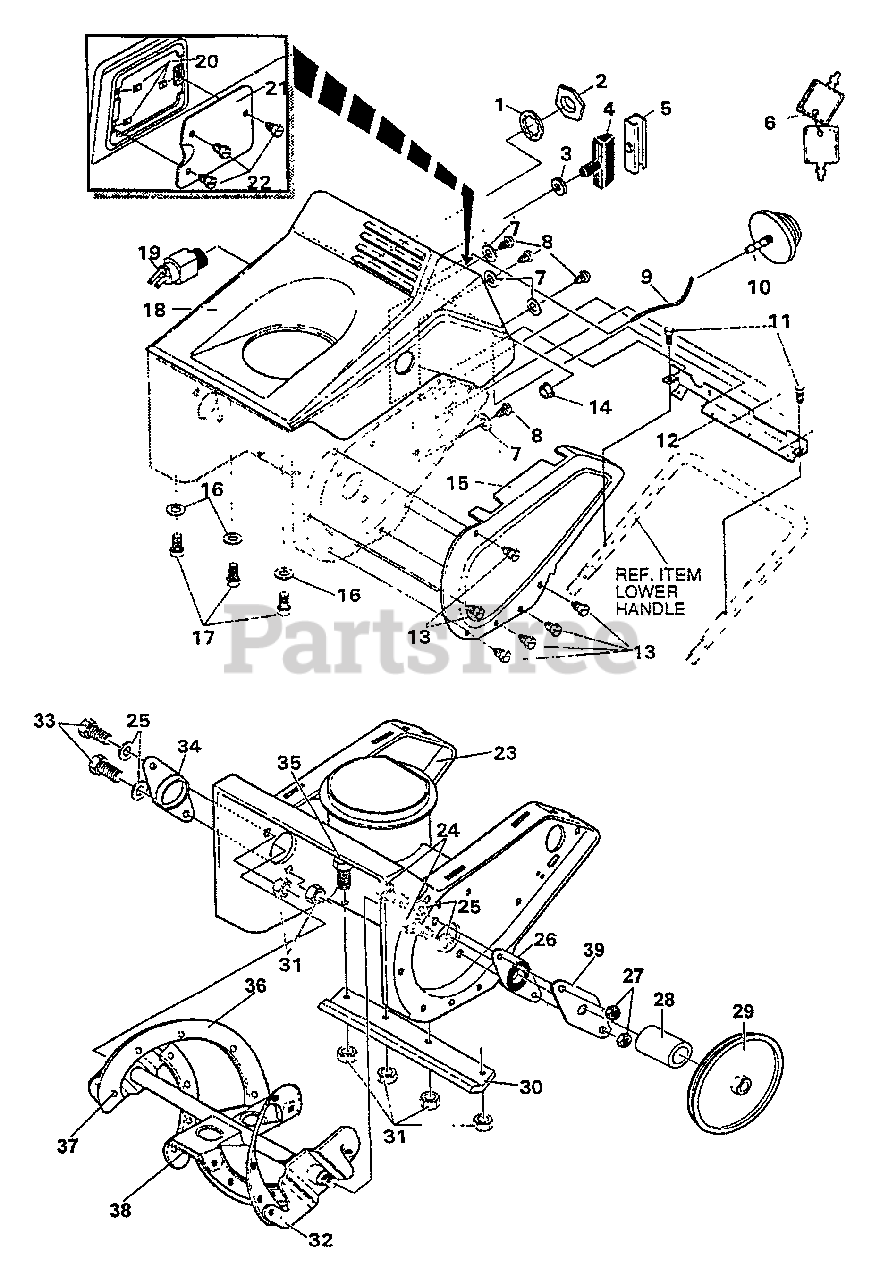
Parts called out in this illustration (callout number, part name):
1	WASHER
2	NUT
3	GUIDE, ROPE
4	KNOB, TEE
4	KNOB, SHORT SHANK
5	INSERT METAL, KNOB
6	KEYS & RING ASSY
7	WASHER
8	SCREW - 10-24×0.63" -- PAN HEAD
10	PRIMER, ENGINE 2CY
11	SCREW - 10-24×0.63" -- PAN HEAD
12	BRACKET
13	SCREW 10-24×38
14	NUT
15	COVER, BELT
16	WASHER
17	SCREW
18	COVER
19	SWITCH, IGNITION
20	NUT
21	DOOR, ACCESS
23	HSNG, ASSY AUG 21"
24	SCREW 1/4 - 20×75 HHC
25	WASHER
26	BRNG & PLATE ASSY
27	NUT, 1/4"-20
28	SPACER
29	PULLEY
30	BLADE, SCRAPER
31	NUT, 1/4"-20
32	AUGER ASSY - 21"
32A	AUGER ASSY
33	SCREW 1/4"-20×0.88
34	BEARING, FLANGE
35	SCREW 1/4"-20×0.63
36	AUGER, BLADE STRIP
37	RIVET, 0.250×.5 IN.
38	AUGER, CENTER BLADE STRIP
39	RETAINER, BEARING
